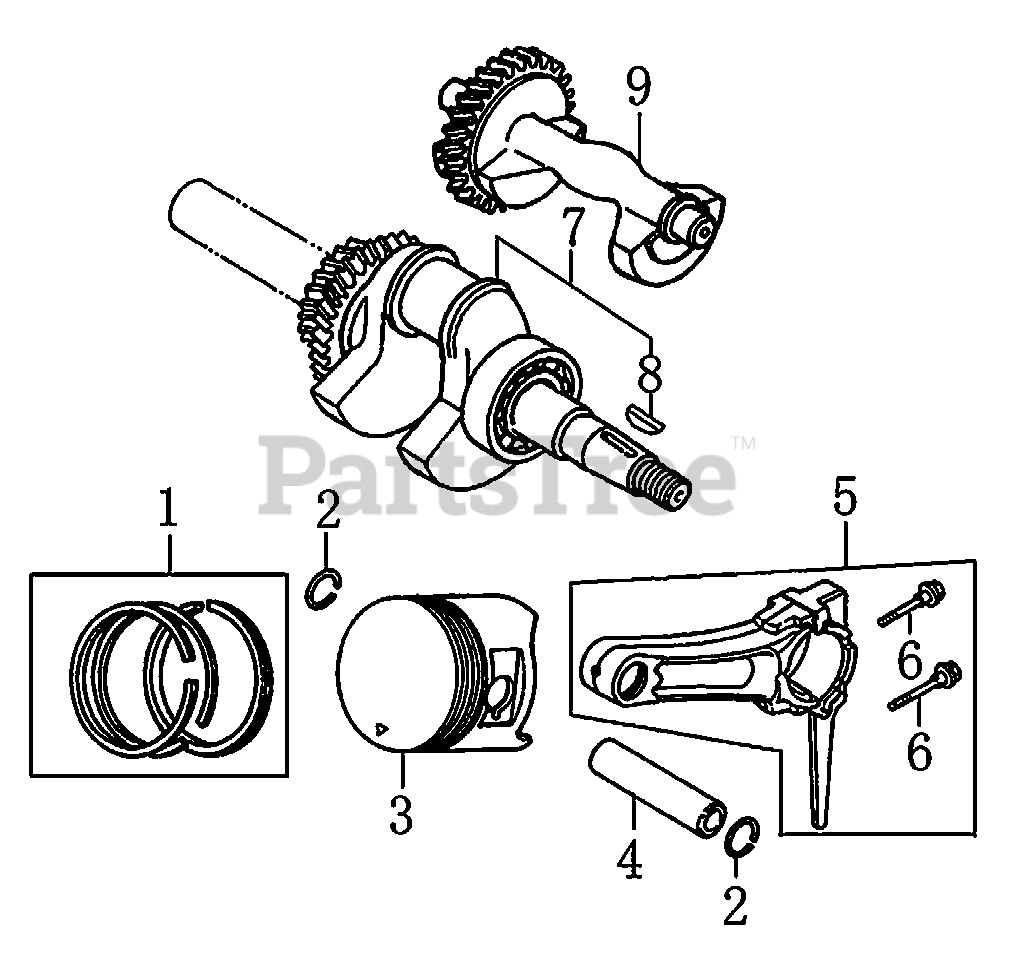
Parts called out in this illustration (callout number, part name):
1	RING SET,PISTON
2	CIRCLIP, PISTON PIN
4	PIN, PISTON
5	CONNECTING ROD ASSY
6	BOLT, CONNECTING ROD
7	CRANKSHAFT ASSY
8	KEY, SPECIAL WOODRUFF
9	WEIGHT, BALANCER
